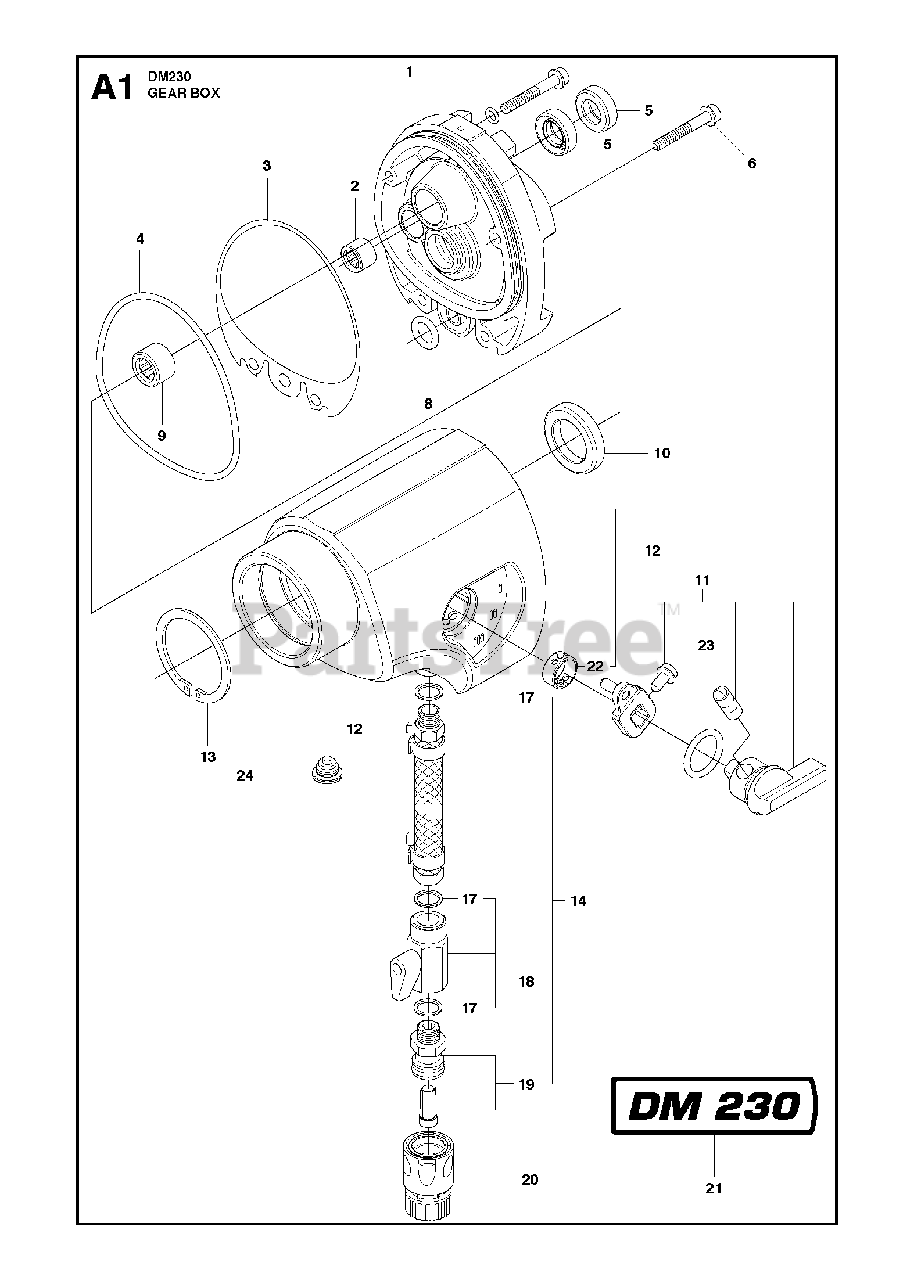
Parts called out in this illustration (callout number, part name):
1	COVER
9	NEEDLE BEARING
20	COUPLERUSA/CANADA
